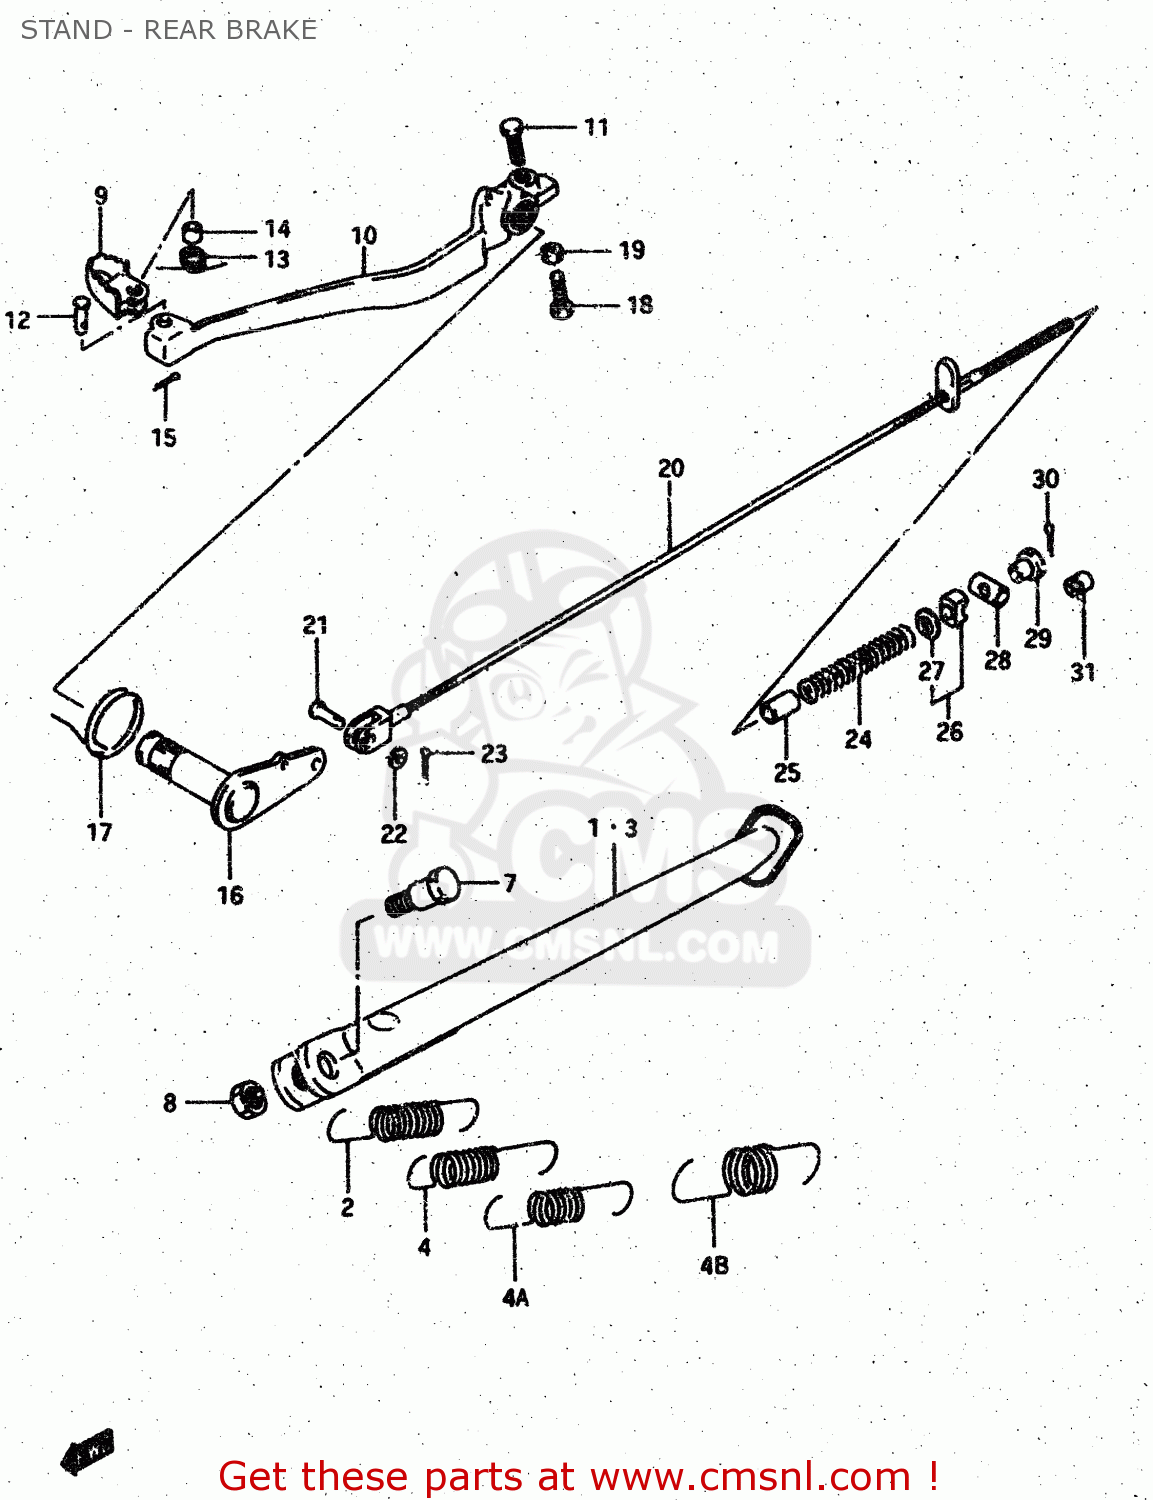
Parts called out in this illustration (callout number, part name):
1	STAND,SIDE
2	SPRING
3	STAND, PROP (BLUE)
4	SPRING
4A	SPRING
4B	SPRING
5	BOLT L:30
6	NUT
7	PEDAL,BRAKE
8	ARM,BRAKE PEDAL
9	BOLT
10	PIN
11	SPRING
12	SPACER(9.2X9X6.5)
13	PIN
14	ARM,BRAKE PEDAL ROD
15	SPRING
16	BOLT (6X27)
17	NUT 6MM
18	CABLE,RR BRAKE
19	PIN(L:17.5)
20	WASHER, LOWER
21	PIN
22	SPRING
23	CUSHION,FR GRILLE,UPPER
24	CUSHION
25	WASHER
26	PIN,BRAKE CABLE ADJUSTER
27	NUT (6MM)
28	PIN
